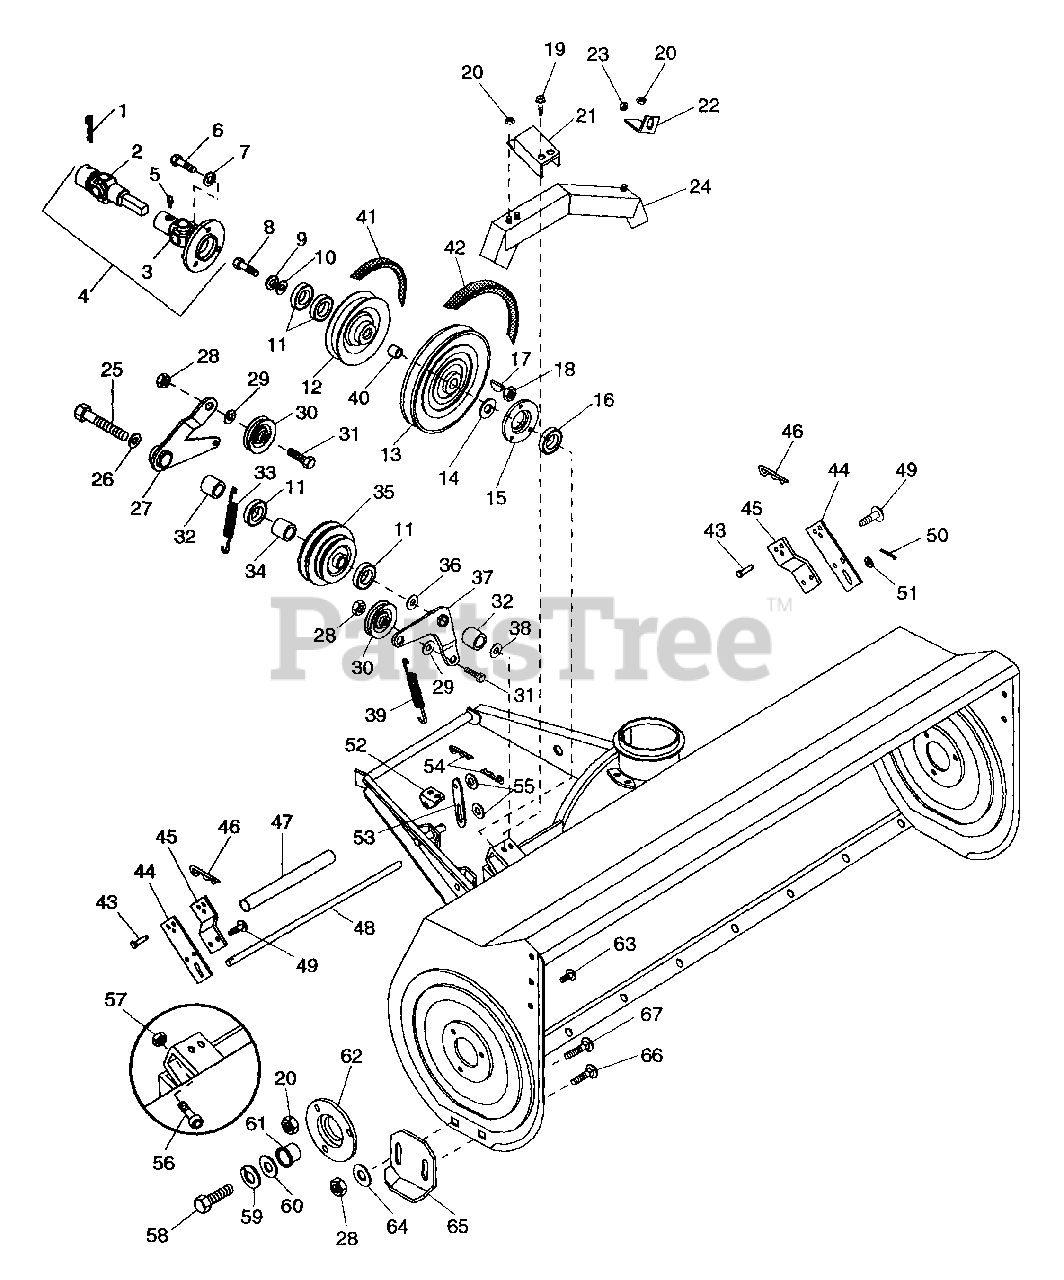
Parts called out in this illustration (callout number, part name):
1	PIN-HAIR INT .18X1.18X3.25 PL
2	UNIVERSAL SPLINE HALF
3	UNIVERSAL PLATE HALF
4	UNIVERSAL SHAFT ASSEMBLY
5	FTG-LUBE .25-28X.256 YWZC
6	BLT-HEX .25-20X.75 PL GR2
7	WSHR-LK .250X.077 HVY PL
8	BLT-HEX .38-16X1.00 PL
9	WSHR-LK .375X.094 MED PL
10	WSHR-FL-STL .438X1.0X.083 PL
11	BRG-BALL .750X1.781X.61
13	PLY-V 10.00 X .88 W/KEY SALEM
14	WSHR-FL-STL .880X1.250X.062
15	BEARING FLANGE
16	BRG-BALL1.0X2.0X.56
17	KEY-WDRF .188X.875X.375 SAE11
18	NUT-LK-CTR .250-20 PL
19	SCR-TAP .250-20X.37 HWH PL TR
20	NUT-LK-FLG .250-20 PL
23	NUT-FLG. .312-18 PL
24	BELT GUARD
25	BLT-HEX .75-10X5.50 GR2
26	WSHR-FL-STL .765X1.250X.093
27	IDLER ARM
28	NUT-LK-CTR .375-16 GR A PL
29	WSHR-FL-STL .406X.875X.135
30	IDLER-FLAT 3.00 X .38 CLK.&CAP
31	BLT-HEX .38-16X1.25 PL GR 2
32	BSHG-SLV .750X1.125X1.062
33	SG-TENS .109X1.00X6.0
34	SPACER .781X1.000X.547
36	WSHR-FL-STL .781X1.500X.188
37	IDLER ARM
38	WSHR-HDND-THRST .755X1.40X.062
39	SG-TENS .109X1.00X6.0
40	SPACER .906X1.125X.453
41	V-BELT, HA-RAW EDGE
42	V-BELT, 4L-RAW EDGE
43	CLEVIS PIN
44	LIFT LINK
45	SUPPORT
46	PIN-HAIR INT .08X.18X1.18
47	TUBE .725 X .875 X 14.00
49	SCR-TAP .312-18X.50 HWH PL TR
50	PIN-COTR .12 X 1.25 PL
51	WSHR-FL-STL .688X1.75X.134PL
52	LIMITING POST
53	LIMITING ARM
54	PIN-HAIR INT .09X.188 PL
55	WSHR-FL-STL .531X1.062X.095 PL
56	SCR-SKH 10-24X.38
57	NUT-LK DUAL FACE 10-24 PL
58	BLT-HEX .50-13X1.00 PL GR2
59	WSHR-LK .500X.151 HVY PL
60	WSHR-FL-STL .511X1.441X.125 PL
61	BSHG-FLG 1.000X1.12X.62X1.50BR
62	BEARING SUPPORT
63	BLT-SERNK SL .25-20X.50 PL
64	WSHR-FL-STL .38X.875X.083 PL
65	RUNNER-SKID SHOE
66	BLT-RDHDSQNK .38-16X.75 SHT PL
67	BLT-RDHDSQSHNK .38-16X1.00 PL
